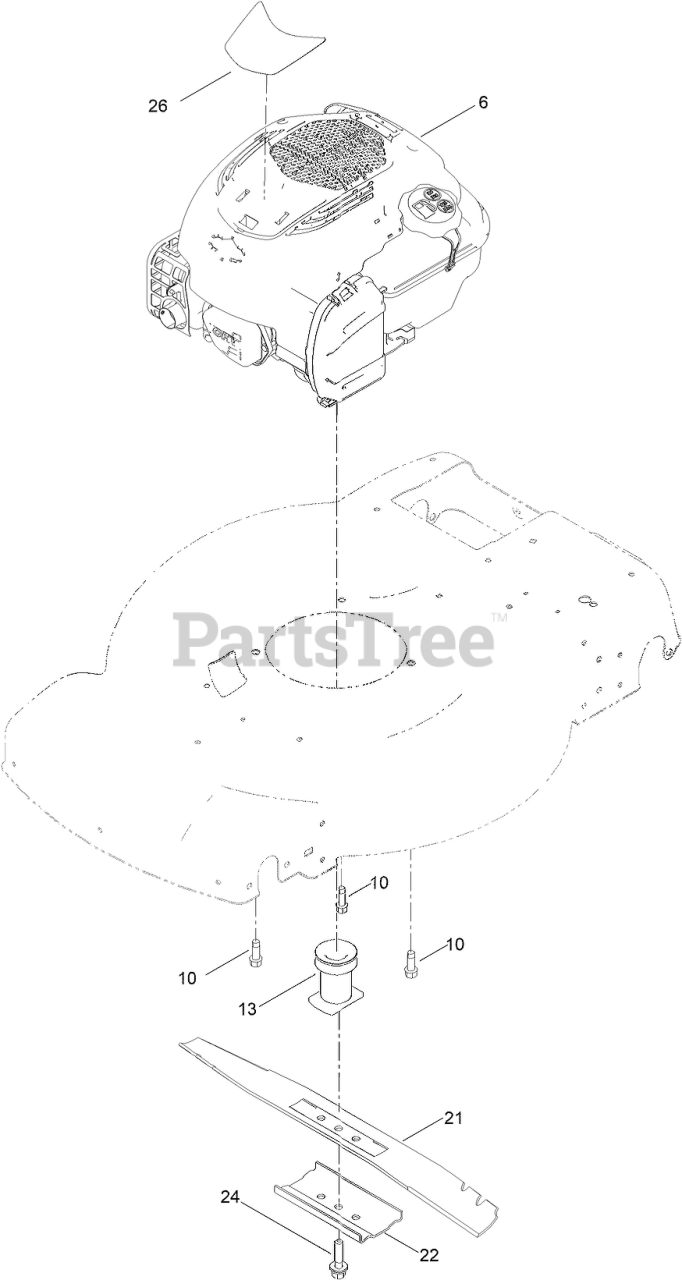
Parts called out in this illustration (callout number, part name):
10	SCREW-THD FORM, HWH
13	DRIVER-BLADE
22	SUPPORT-BLADE
24	BOLT-BLADE
26	DECAL - BRIGGS 725 EX
